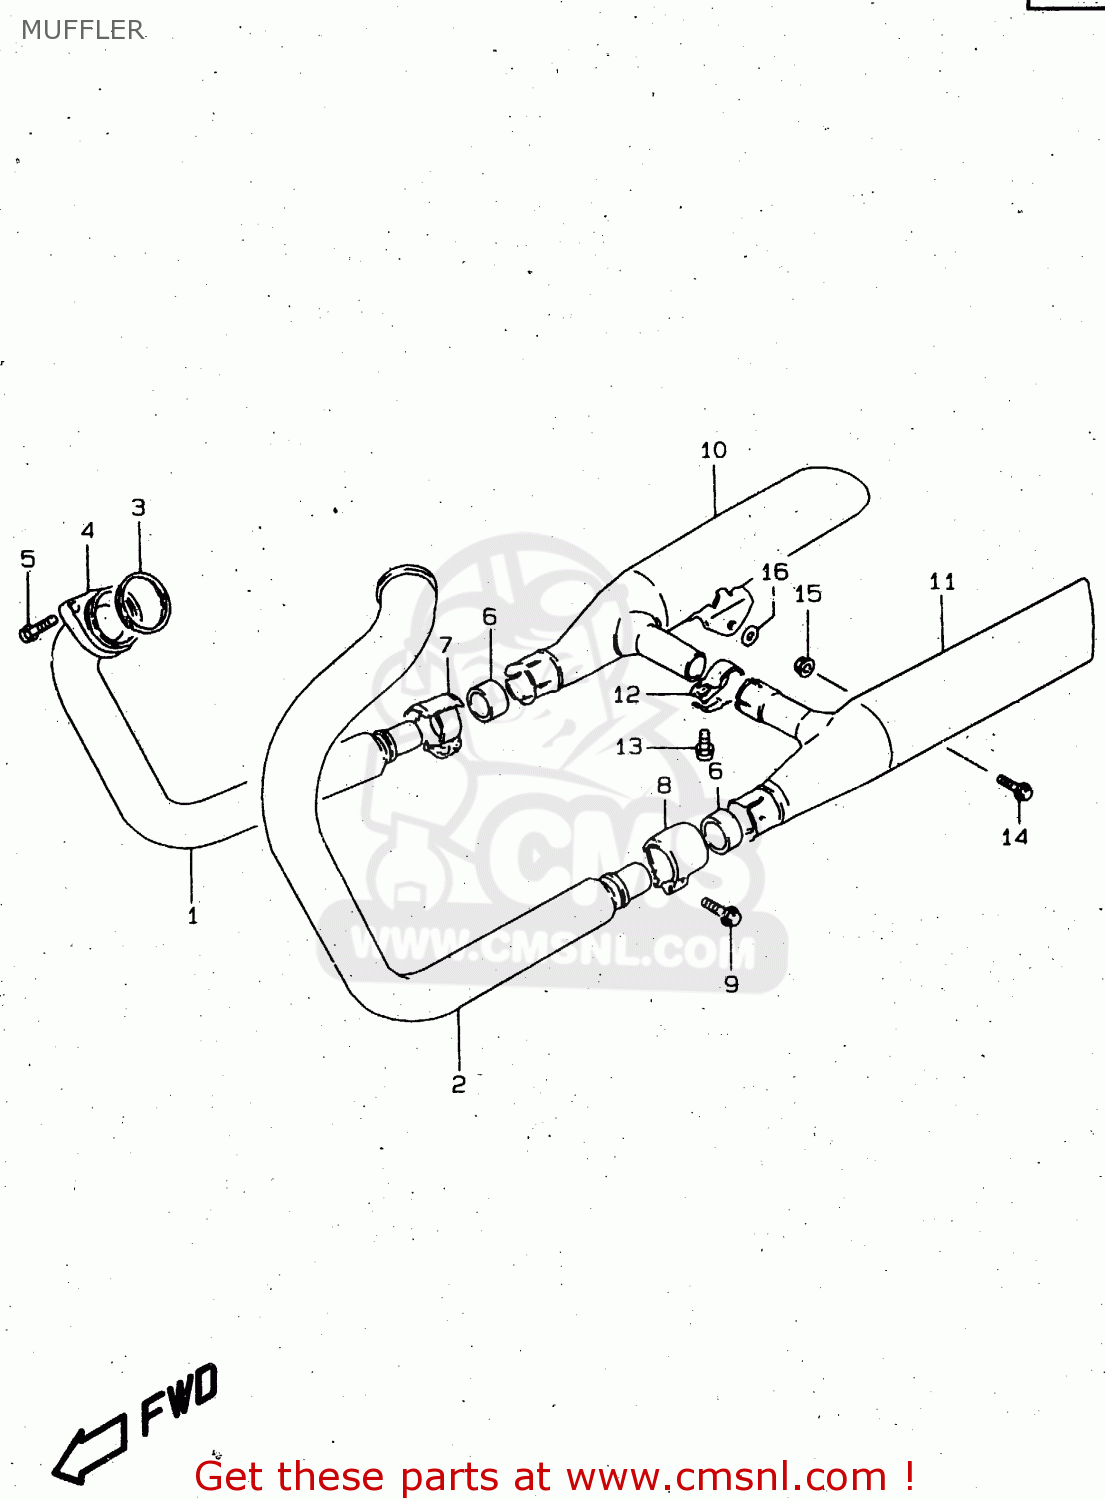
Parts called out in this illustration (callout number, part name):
1	PIPE,EXHAUST,R
2	PIPE,EXHAUST,L
3	GASKET,EXHAUST PIPE (NAS)
4	CLAMP,EXHAUST PIPE
5	BOLT(8X35)
6	CONNECTOR,EXHAUST PIPE
7	CLAMP,MUFFLER CONNECTOR,R
8	CLAMP,MUFFLER CONNECTOR,L
9	BOLT,G/S SWITC
10	BODY,MUFFLER,R
11	BODY,MUFFLER,L
12	CLAMP,EXHAUST COUPLER
13	BOLT
14	BOLT
15	NUT
16	WASHER(8.5X18X3.20)
